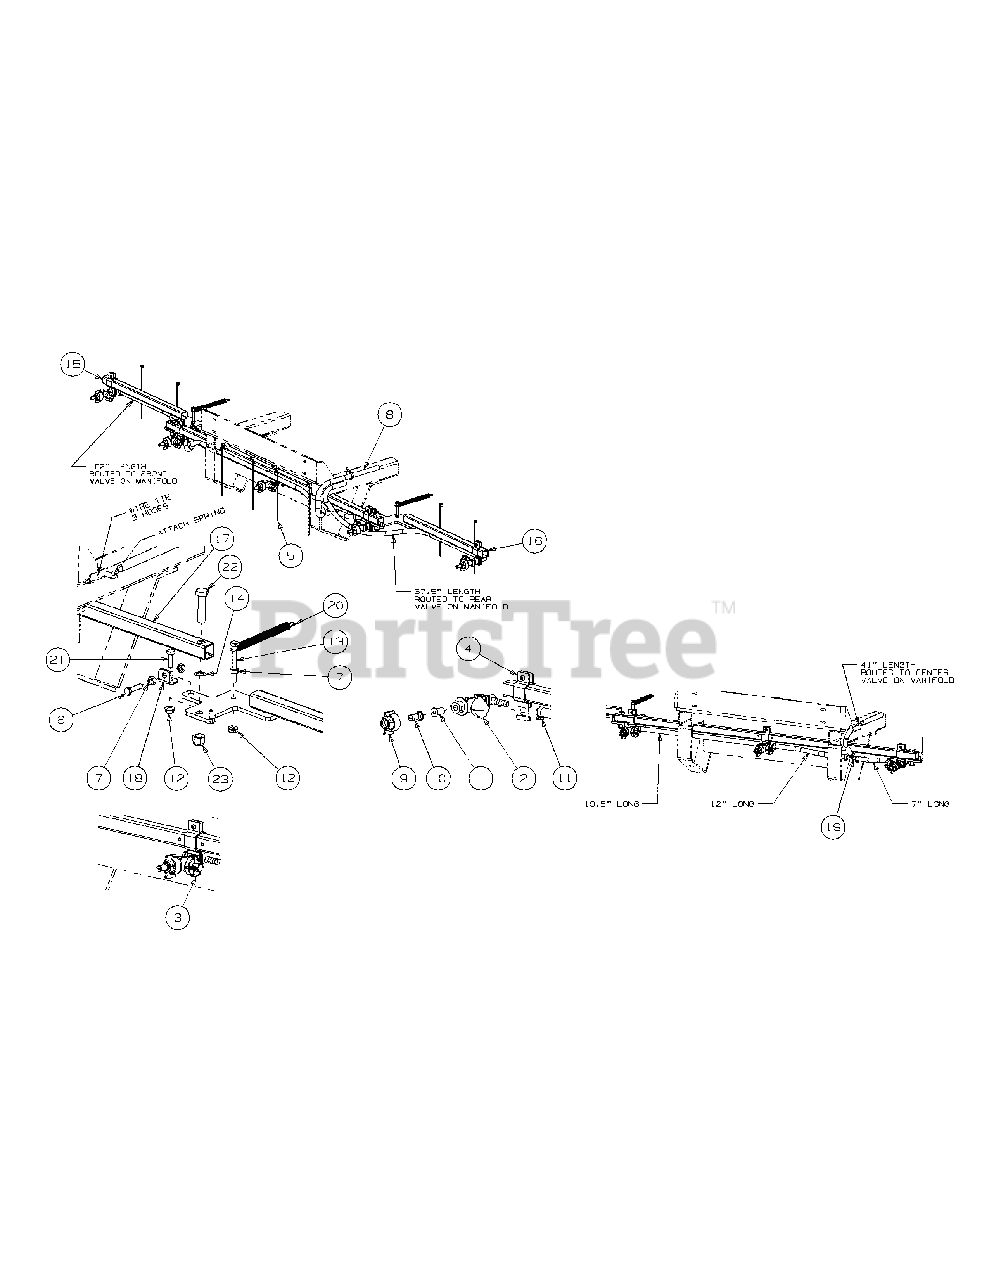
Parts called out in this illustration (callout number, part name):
1	Strainer Screen, 50 Mesh, SS
2	Nozzle, Single Body, Dry Boom
3	Nozzle, Double Body, Dry Boom
4	Clamp, Body Nozzle
5	Cable Tie
6	HHCS, 5/16-18 x 1.25
7	Nut, 5/16-18
9	Cap
10	Nozzle, Turbo Flood Jet - Red - Very Fine
10	Nozzle, Turbo Flood Jet - Brown - Med
10	Nozzle, Turbo Flood Jet - White - Extremely Coarse
11	Hose Clamp
12	Nut, Lock, HexFlange, 5/16-18
13	HHCS, 5/16-18 x 2.75
14	Washer, .50 ID x .75 OD x .031
15	Boom Arm Assembly, LH
16	Boom Arm Assembly, RH
18	Boom Stop Arm
19	T-Fitting, 3/8
20	Extension Spring
21	HHCS, 5/16-18 x 1.0
22	HHCS, 1/2-13 x 2.00
23	Nut, 1/2-13
